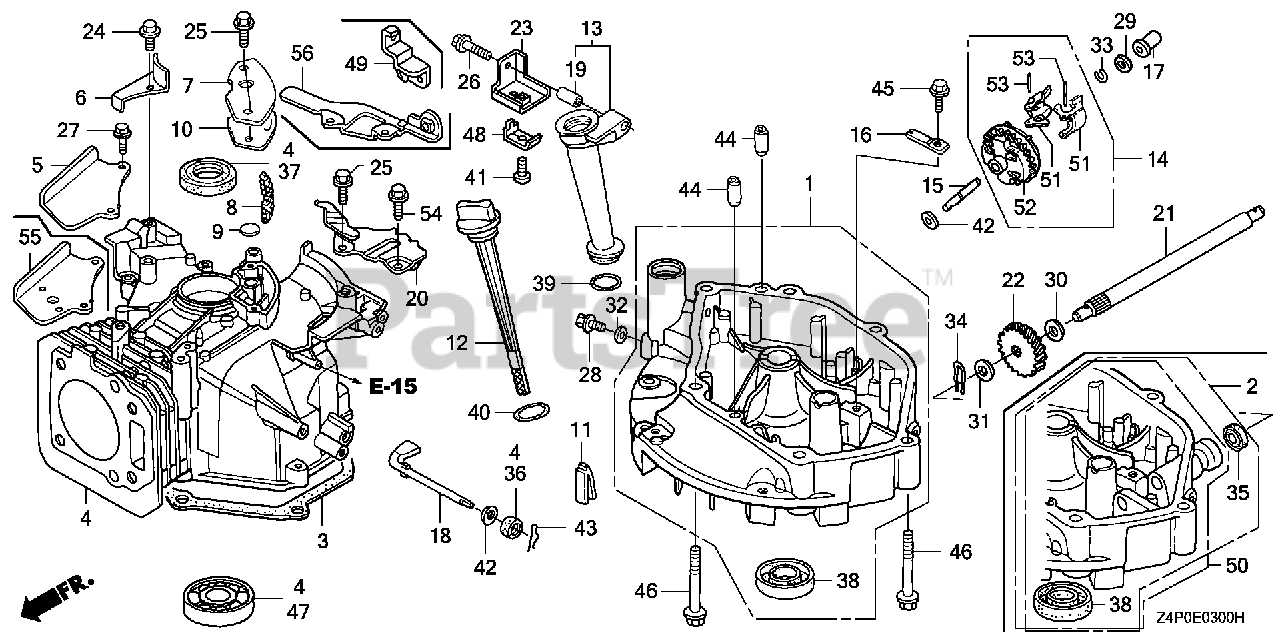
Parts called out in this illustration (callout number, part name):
1	PAN ASSY., OIL
3	GASKET, OIL PAN
3	GASKET, OIL PAN (NINGBO SIL GASKET)
4	CYLINDER ASSY.
5	PLATE, GUIDE
6	PLATE A, GUIDE
7	COVER, BREATHER
8	FILTER, BREATHER
9	VALVE, BREATHER
10	GASKET, BREATHER COVER
11	RUBBER, OIL RETURN
12	GAUGE, OIL LEVEL Use up to Engine SN 1257294.
13	EXTENSION, OIL FILLER (106MM)
14	GOVERNOR ASSY.
15	SHAFT, GOVERNOR HOLDER
16	PLATE, GOVERNOR SHAFT HOLDER
17	SLIDER, GOVERNOR
18	SHAFT, GOVERNOR ARM
19	COLLAR, EXTENSION Use up to Engine SN 1257294.
20	STAY, TANK
24	BOLT, FLANGE (6X12) (CT200)
25	BOLT, FLANGE (6X14)
26	BOLT, FLANGE (6X32)
27	BOLT, FLANGE (6X20) (CT200)
28	BOLT, DRAIN PLUG
29	WASHER, THRUST (6MM)
32	WASHER, DRAIN PLUG (10.2MM)
33	CLIP, GOVERNOR HOLDER
36	OIL SEAL (6X11X4) (ARAI)
37	OIL SEAL (25X38X7) (ARAI)
38	OIL SEAL (25.4X40X7)
39	O-RING (22.1X2.2)
40	O-RING (25.5X3)
42	WASHER, PLAIN (6MM)
43	PIN, LOCK (8MM)
44	PIN A, DOWEL (8X14)
45	BOLT, FLANGE (6X12) Use from Engine SN 2086984.
46	BOLT, FLANGE (8X50)
47	BEARING, RADIAL BALL (6205)
51	WEIGHT, GOVERNOR
52	HOLDER, GOVERNOR WEIGHT
53	PIN, GOVERNOR WEIGHT
54	BOLT, FLANGE (6X14)
